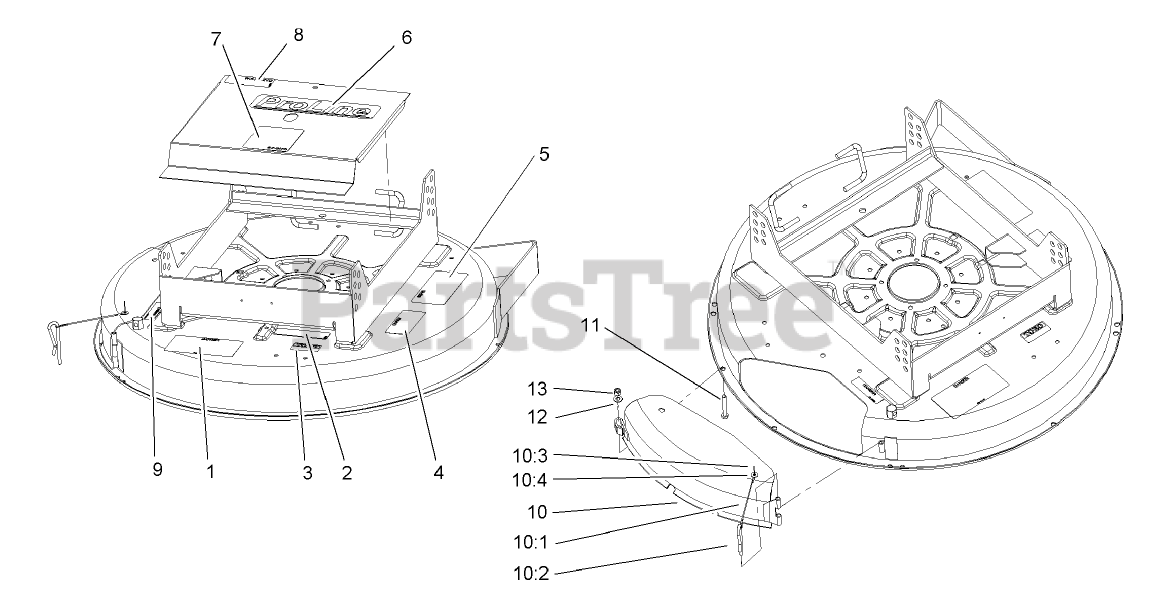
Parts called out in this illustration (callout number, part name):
1	DECAL-DANGER, THROWN OBJECT
2	DECAL-DANGER
3	DECAL-STD, SAFETY
4	DECAL-TORQUE
5	DECAL-HOC
7	DECAL
8	DECAL-HOT
9	DECAL-DANGER
10	MULCHER COVER ASM
10:1	LANYARD
10:2	PIN-LOCKING, CHUTE
10:3	WASHER-PLAIN
10:4	RIVET-BLIND
11	SCREW-HH
12	WASHER-PLAIN
13	NUT-LOCK, NI
